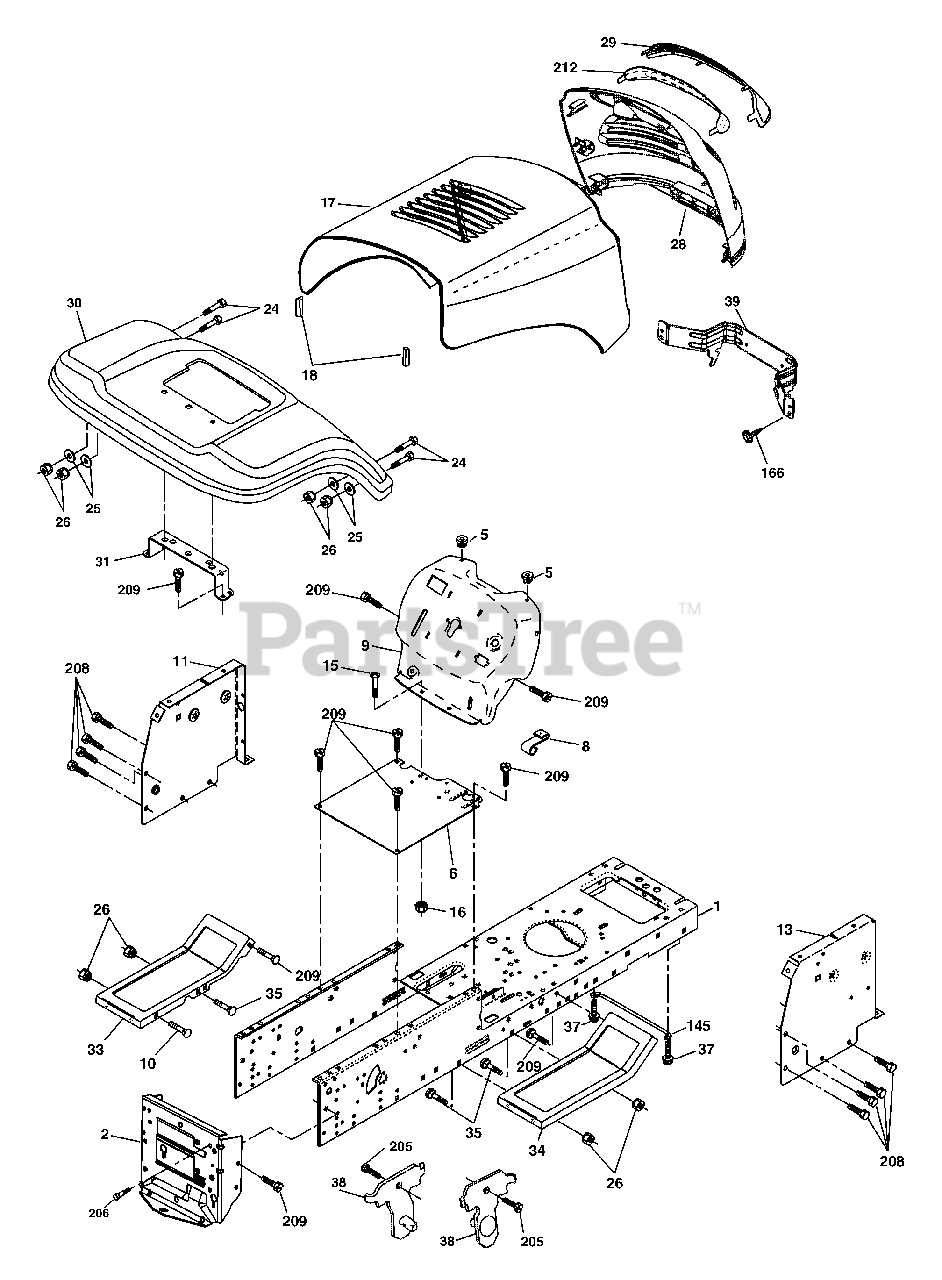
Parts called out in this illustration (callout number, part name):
1	Chassis
2	Drawbar, Stretch
5	Bumper, Hood/Dash
6	Saddle
8	Clip Retainer Slide-On
9	Dash
10	Bolt, Carriage 3/8-16 x 1
11	Panel Dash LH
13	Panel Slkscr Dash RH
15	Screw Mach TRHD 5/16-18 unc x 3/4
16	Nut Keps 5/16-18 unc
17	Hood
18	Bumper Hood
24	Bolt Fin Hex 3/8-16 unc x 1 Gr. 5
25	Washer 13/32 x 13/16 x 12 Ga.
26	Nut Lock Hex w/Ins 3/8-16 unc
28	Grille/Lens Asm.
29	Lens Grille Bar
30	Fender
31	Bracket Fender Repl 109873X
33	Footrest Pnt LH
34	Footrest Pnt RH
35	Bolt Rdhd Sht Sqnk 3/8-16 x 3/4
37	Screw Thdrol 5/16-18 x 1/2 TYT
38	Bracket Asm. Pivot Mower
39	Bracket Pivot
145	Rod Pivot Chassis/Hood
205	Screw Thdrol 3/8-16 x 1/2
206	Bolt Shoulder 5/16-18
208	Screw Thdrol 3/8-16 x 1/2
209	Screw Hex Wsh Thdrol 3/8-16
212	Insert Lens Reflect
278	Screw 10 x 3/4 Single Lead Hex
278	Plug Button Blk 359 Dia Choke
278	Plug Dome Plastic
